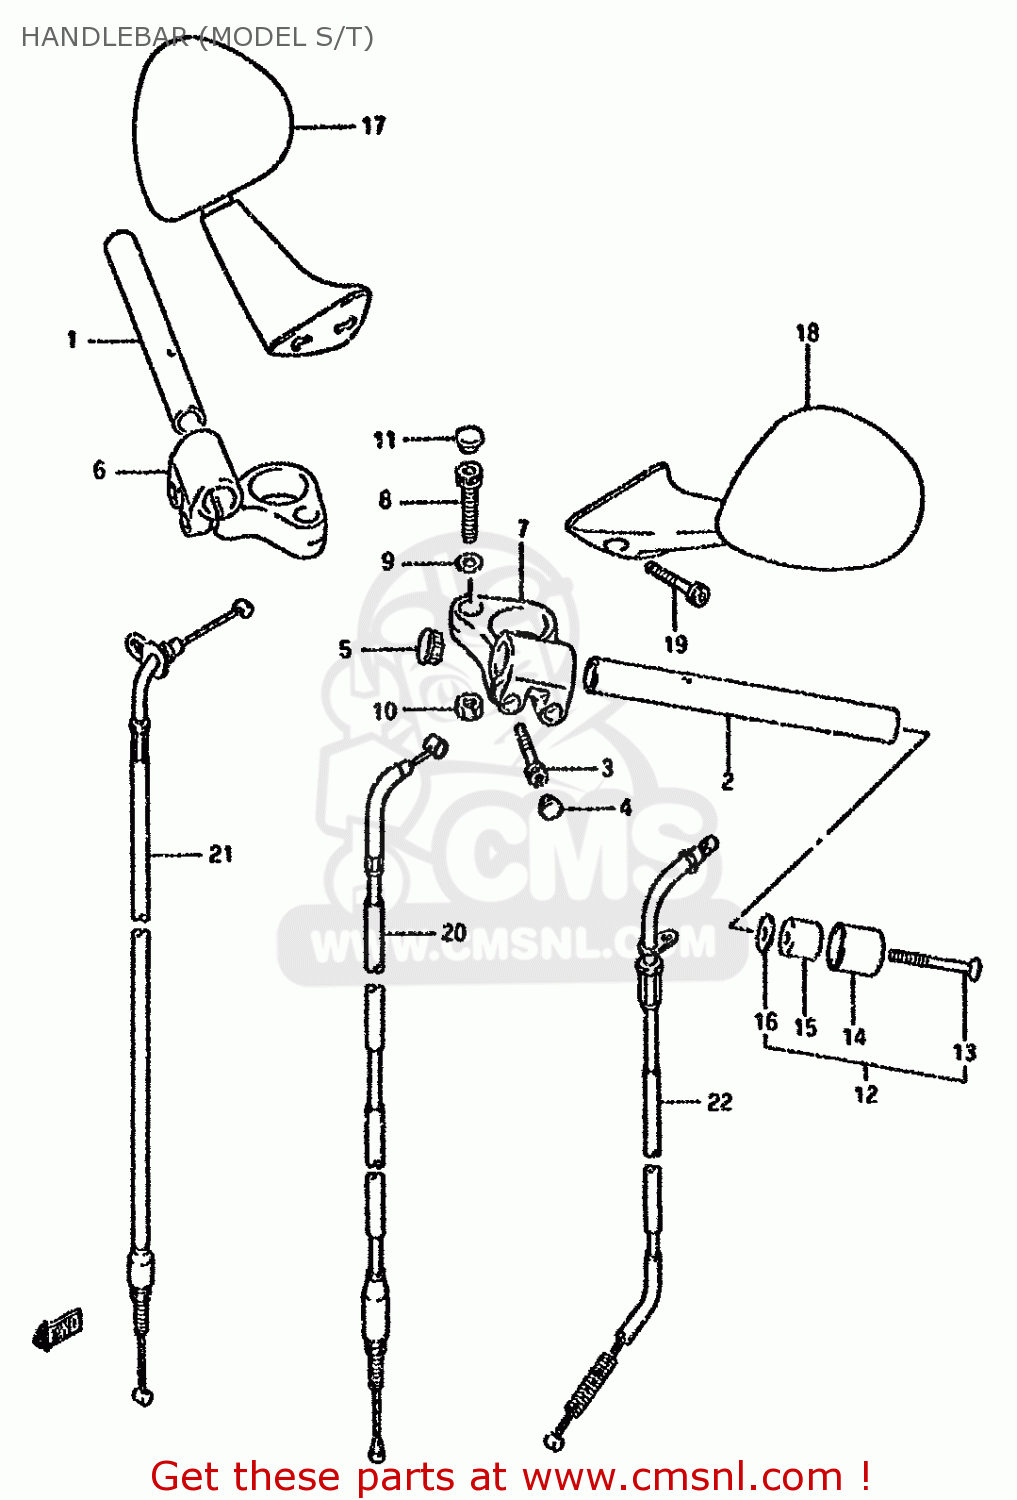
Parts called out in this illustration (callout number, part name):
1	HANDLEBAR,R
2	HANDLEBAR,L
3	BOLT
4	CAP(OD:10)
5	CAP,HANDLEBAR
6	HOLDER,HANDLEBAR,RIGHT
7	HOLDER,HANDLEBAR,LEFT
8	BOLT 10X45
9	WASHER
10	NUT
11	CAP(OD:20)
12	BALANCER SET,HANDLEBAR
13	SCREW
14	CAP,BALANCER
15	BALANCER,HANDLE
16	SPACER,BALANCER
17	MIRROR ASSY,RH
18	MIRROR ASSY,LH
19	BOLT
20	CABLE ASSY,CLUTCH
21	CABLE ASSY,THROTTLE
22	CABLE,STARTER
